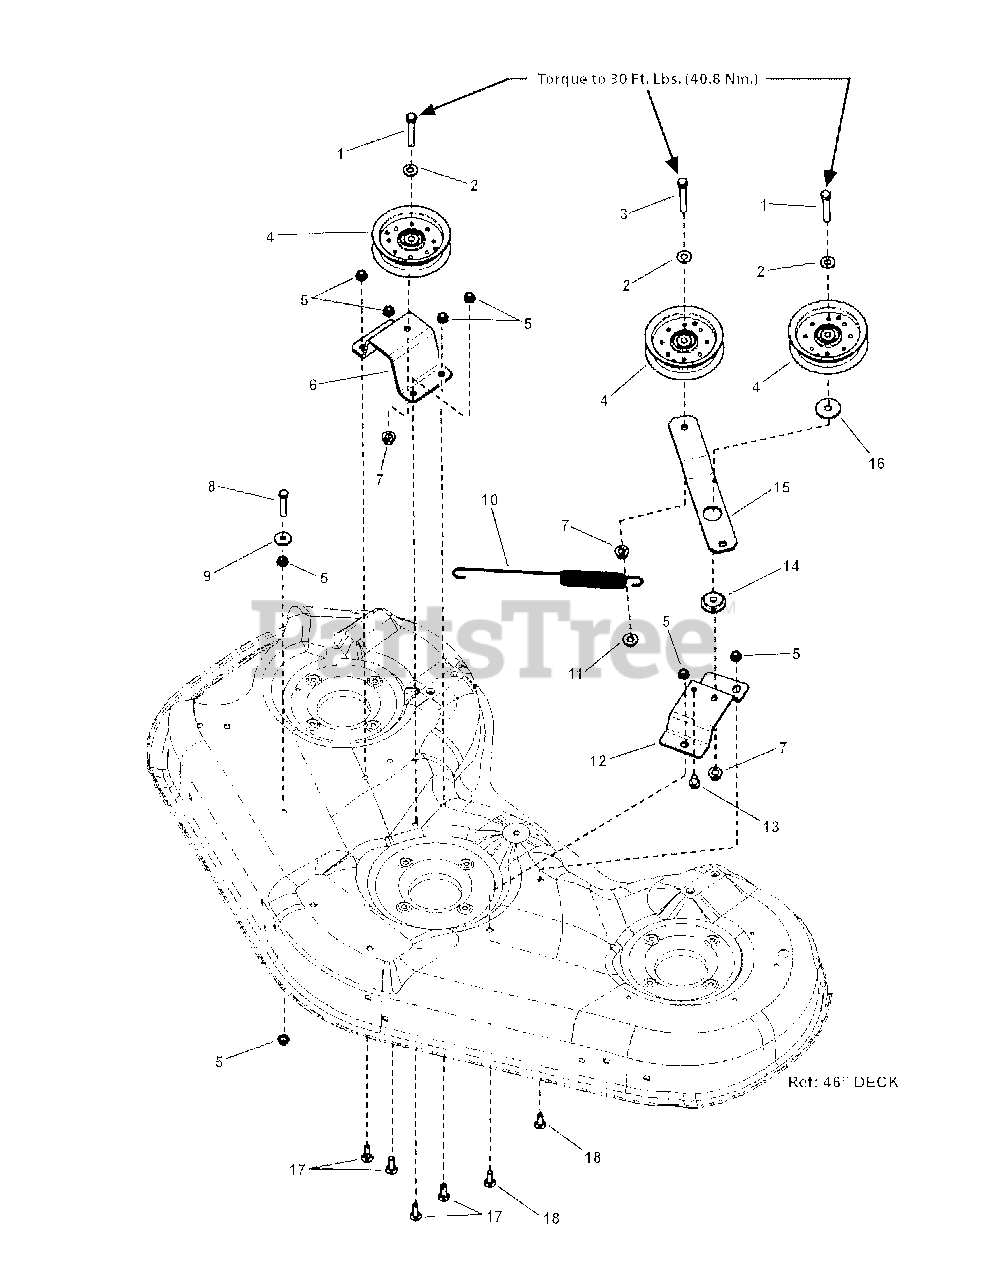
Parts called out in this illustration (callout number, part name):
1	SCREW, 3/8-16 x 2-1/2" Hex Head Cap, GR 5 Black
2	WASHER, 3/8" Flat (.41 ID x .87 OD)
3	SCREW, 3/8-16 x 2-1/2" Hex Head Cap GR 5 Black
4	PULLEY, Idler 46/52, Mowers
5	NUT, 5/16-18 Hex Flange Lock, Large, Black
6	BRACKET, Fixed Idler, Rear, 46"
7	NUT, 3/8-16 Hex Flange lock, GR F, BZ
8	SCREW, 5/16-18 X 1-3/4"Hex Head Cap, GR 5 Yellow Zinc
9	WASHER, 5/16" Flat (.341 ID x 1.00 OD x .13 Thick) Black
10	SPRING, Extension, PTO
11	NUT, 3/8-16 Hex Flange Lock, Large, Black
12	BRACKET, Idler Mount Front 46/52, Black
13	SCREW, 5/16-18 x 3/4" Hex Washer Head Self-Tap, Black
14	SPACER, .406 ID x 1.50 OD x .350 Thick, PM
15	ARM, Idler, 46/52 RZT
16	WASHER, .406 x 1.50 x .120 Flat, Yellow Zinc
17	BOLT, 5/16-18 x 1" Round Head Short Square Neck, GR 5 Zinc
18	BOLT, 5/16-18 x 7/8" Round Head Short Square Neck, GR 5, Black
